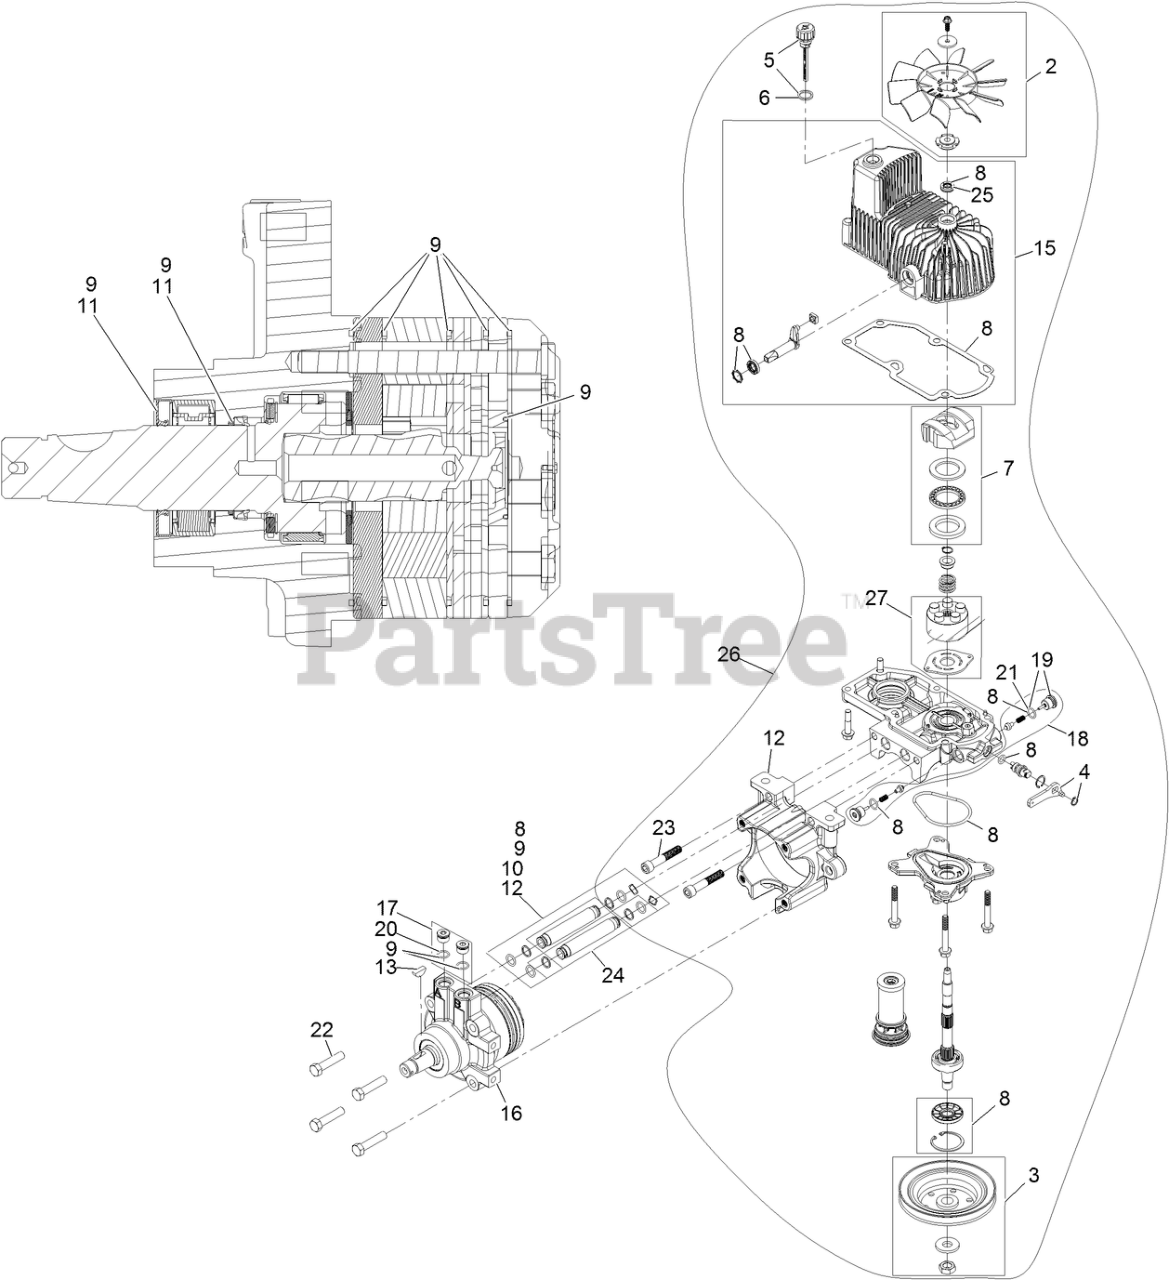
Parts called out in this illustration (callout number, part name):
2	KIT, 7.8 IN FAN
3	PULLEY KIT
4	HANDLE-BYPASS VALVE, HYDRO
5	DIPSTICK-HYDRO W/GASKET
6	GASKET-DIPSTICK, HYDRO
7	SWASH BLOCK KIT
8	KIT, PUMP SEAL
9	MOTOR SEAL KIT
10	TUBE SEAL KIT
11	OUTPUT SHAFT SEAL KIT
12	NOSE CUP-UHT
13	KEY-WOODRUFF
15	KIT, HOUSING-HYDRO LH
16	MOTOR-HYDRAULIC LH 240CC
17	MAGNETIC PLUGS SERVICE KIT
18	ASM, CHECK VALVE
19	PLUG-CHECK (W/O-RING)
20	O-RING
21	O-RING-CHECK VALVE
22	SCREW HH
23	SCREW-HSH
24	HYDRAULIC TUBE KIT
25	SEAL-FAN DRIVE
26	KIT, PUMP SECTION 12CC LH
27	KIT - 12CC PORT PLATE,ROTATE GRP
